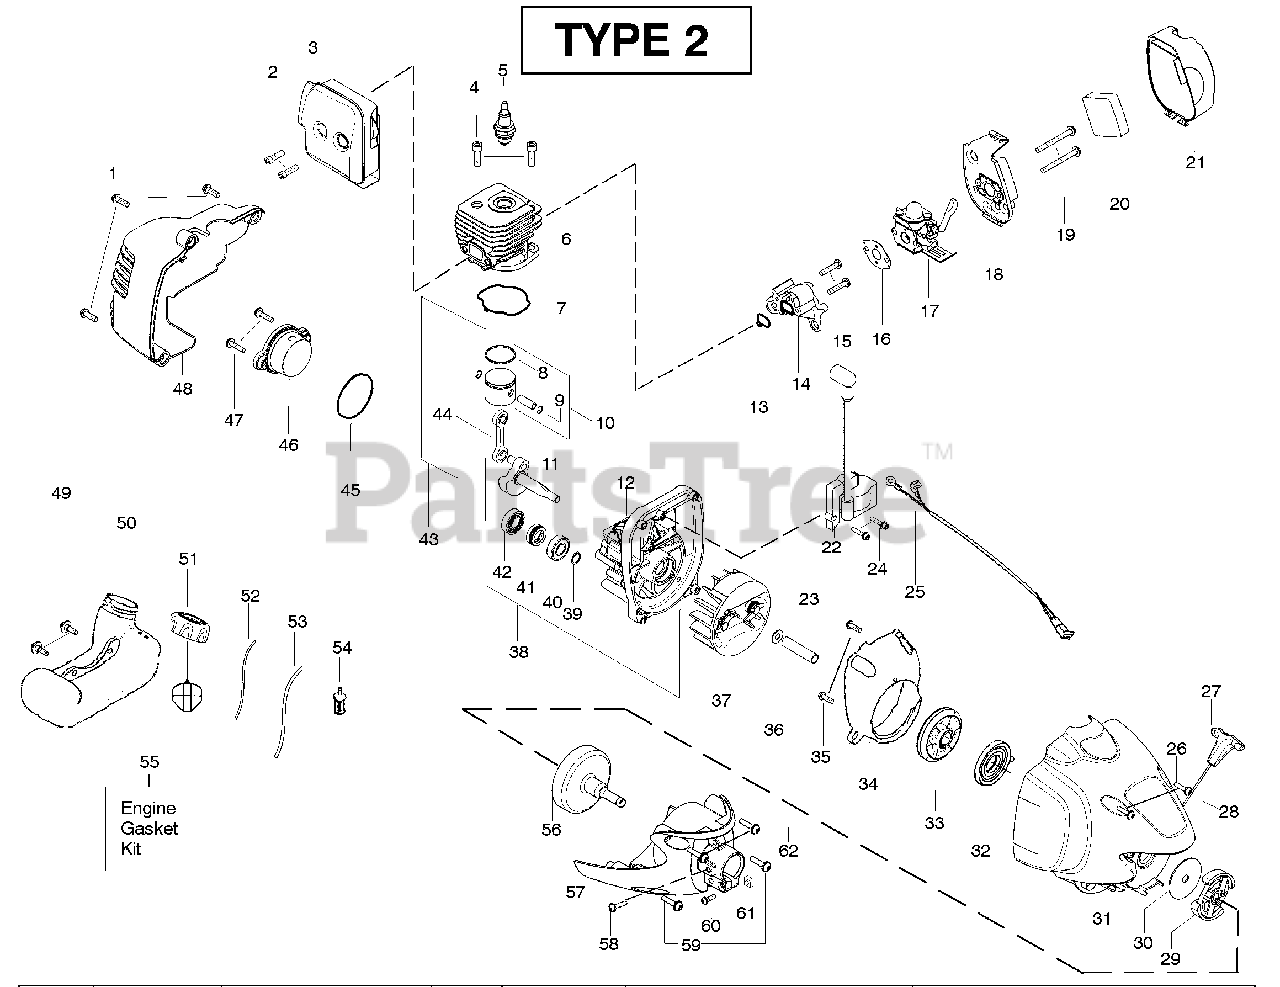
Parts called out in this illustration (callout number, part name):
2	Bolt-Muffler
3	Assy-Muffler/Shield
4	Screw-Cylinder
5	Spark Plug (RCJ 6Y)
6	Cylinder
7	Seal-Cylinder (kit)
8	Piston Ring
9	Retainer-Piston Pin
10	Kit - Piston
11	Assy-Crankshaft
12	Assy-Crankcase
13	Seal-Cyl/Carb.(kit)
14	Adapter-Carb.
16	Gasket-Carb. (kit)
17	Kit-Carb.(C1U-W19)
20	Foam-Air Filter
21	Cover-Air Box
22	Ignition Module
23	Spacer-Flywheel
25	Assy-Switch wire
27	Handle-Starter
28	Kit - Rope
29	Assy-Clutch
30	Washer-Clutch
31	Assy.-Fan Hsg
32	Spring-Starter
33	Kit-Starter Pulley
36	Washer-Clutch Flat
37	Assy-Flywheel
38	Assy-C'case & C'shaft
39	Retain. Ring-C'shaft
40	Outer Bearing
41	Seal-C'shaft
42	Inner Bearing
43	Kit-piston/rod
44	Kit-Conn. Rod
45	O-Ring-C'case (kit)
46	Assy-Plug
48	Shroud-Rear
49	Retainer-Tank Screw
50	Assy-Fuel Tank
51	Assy-Fuel Cap
52	Kit-Fuel Line (Small)
53	Kit-Fuel Line (Large)
54	Assy-Fuel Pickup
55	Kit-Engine Gasket
56	Assy-Clutch Drum
57	Assy-Clutch Cover
58	Screw-Align
60	Screw 12-24
61	Nut 12-24
